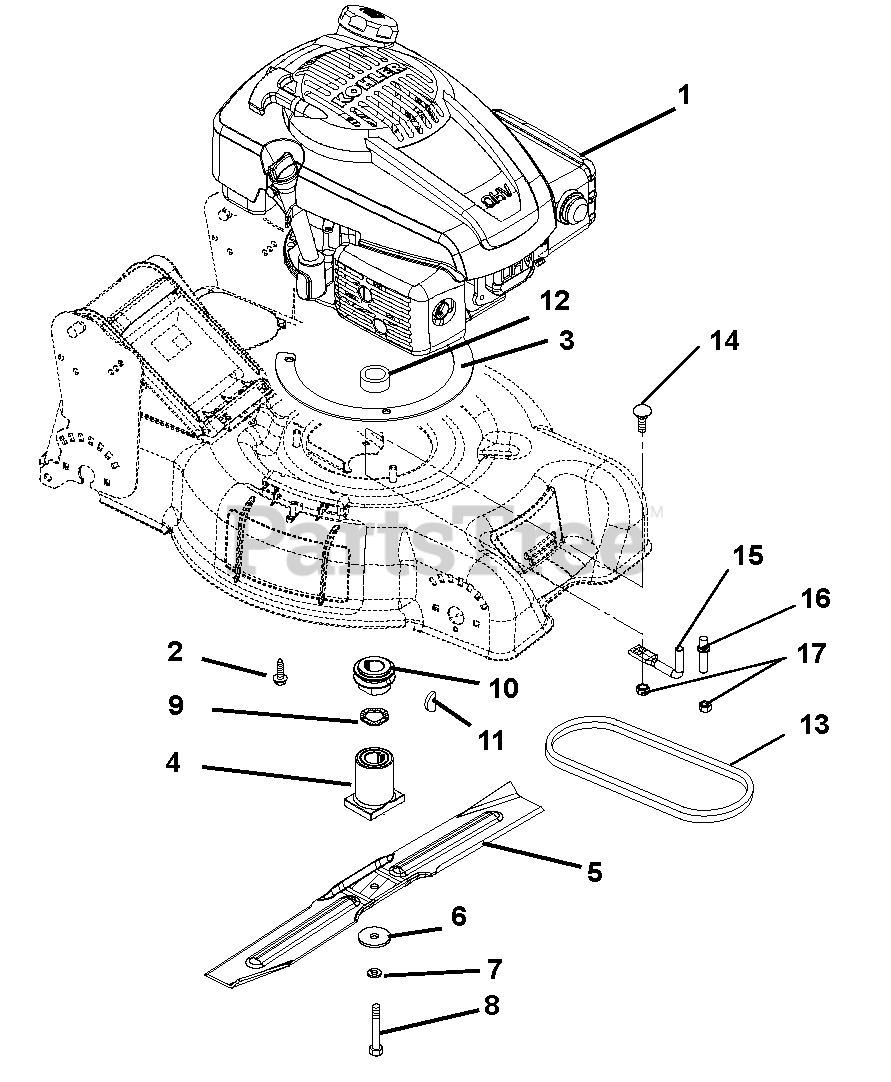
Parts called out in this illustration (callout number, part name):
1	Engine, Kohler XT-7(911220, 222)
2	Screw, Tapping .38-16X1.00 Hex Washer Head
3	Ring, Engine Bolt
4	Adapter, Blade Hub
5	21" Mower Blade
6	Washer, Flat Steel .39 x 1.5 x .125
7	Washer, Locking .38 x .094 Regular
8	Bolt, .38-24 x 2.5 Grade 8
9	Washer, Wave .885 x 1.311 x .125
10	Pulley, Sintered Iron LM (911222, 226)
11	Key, Woodruff .156 x .625 x .25
12	Spacer, .875 x 1.125 x .551
13	Belt, 3L Wrapped 37.00"
14	Bolt, Round Head Square Neck .25-20 x .50 Grade 5
15	Finger, Belt
16	Finger, Belt
17	Nut, Locking-Flange .250-20
